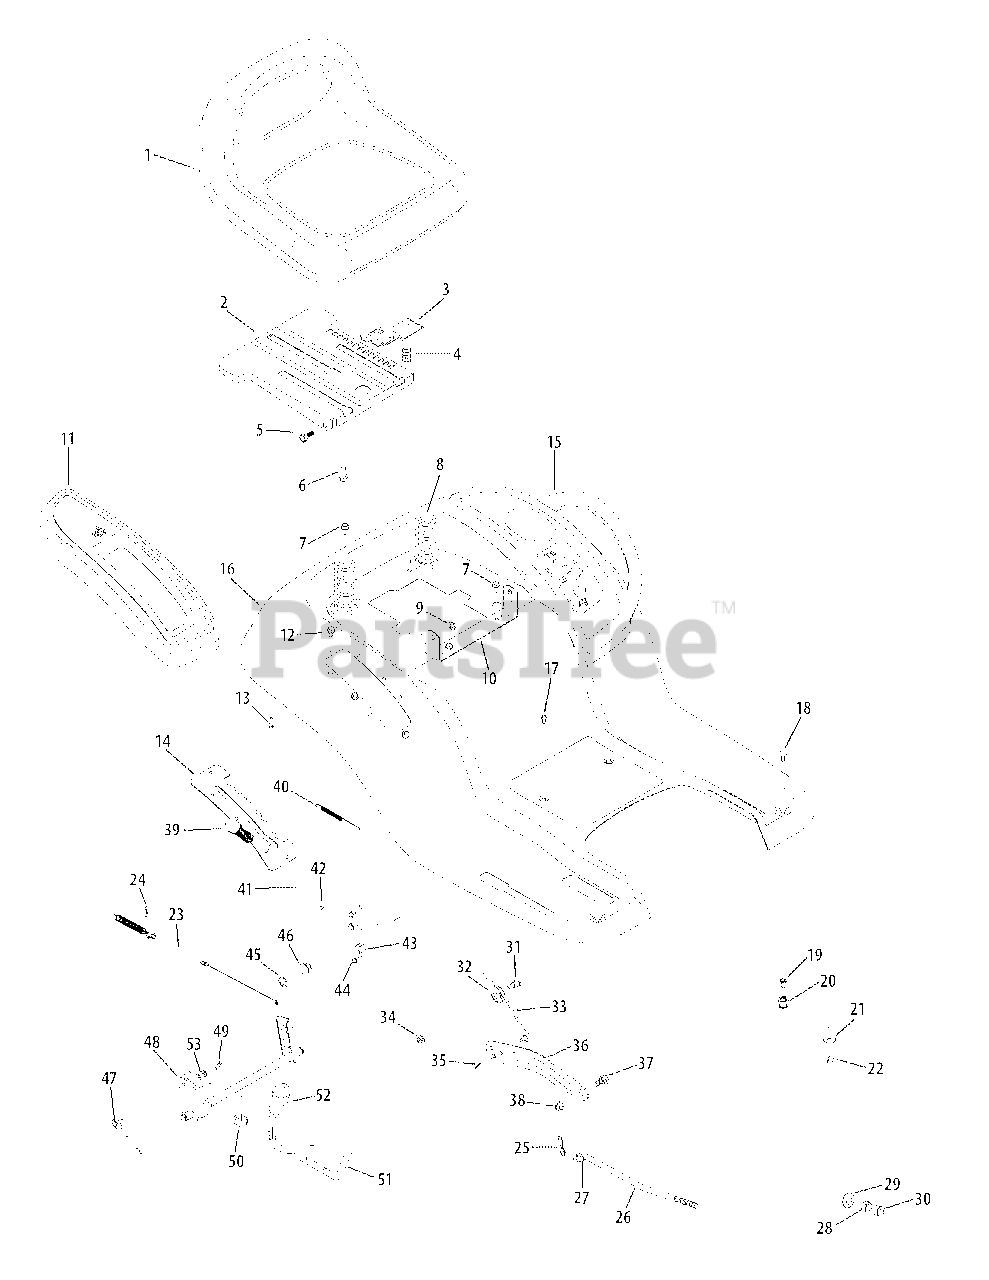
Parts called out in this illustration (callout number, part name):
1	Medium Back Seat
2	Seat Mounting Bracket
3	Seat Adjustment Lever
4	Compression Spring, .68 x 1.065 x .055
5	Shoulder Screw, 5/16-18 x .437 x .268
6	Hex Flange Bolt, 3/8-16 x .875
7	Hex Washer Screw, 5/16-18 x .750
8	Compression Spring, 1.71 x 3.735 x .238
9	Flange Lock Nut, 5/16-18
10	Seat Pivot Bracket
11	Fender Cover. RH
12	Hex Washer Screw, 5/16-18 x .750
13	Hex Washer Screw, 1/4-15 x .750
14	Manual PTO Lift Bracket
15	Fender Cover, LH
17	Hex Washer Screw, 1/4-20 x .500
18	Screw, 5/16-18 x 1.25
19	Flange Spacer, .3125 x .4375 x .625
20	Grommet, .4375 x .750
21	Flat Washer, .344 x 1.0 x .063
22	Flange Lock Nut, 5/16-18
23	PTO/Deck Engagement Cable
24	Bow-Tie Cotter Pin
25	Cotter Pin, 3/16 x 1.00
26	Deck Lift Rod
27	Flat Washer, 1/2 x 1.25 x .10
28	Bell Washer
29	Hex Nut, 1/2-13
30	Hex Lock Nut, 1/2-13
31	Shoulder Screw, 5/16-18 x .437 x .470
32	Cable Roller Pulley
33	Lift Cable
34	Flange Lock Nut, 5/16-18
35	Cotter Pin, 3/32 x 1.0
36	Lift Arm, LH
37	Shoulder Bolt, 3/8-16 x .625 x .175
38	Flange Lock Nut, 3/8-16
39	Grip
40	Extension Spring, .38 x 5.6
41	PTO Handle & Bracket Assembly
42	Shoulder Screw, #10-32 x .500
43	PTO Bearing
44	Hex Washer Screw, 1/4-20 x .500
45	E-Type Ring
46	Hex Flange Bearing
47	Lift Cable
48	Lift Shift Assembly
49	Cotter Pin, .072 x 1.13
50	Torsion Spring
51	Lift Handle
52	Handle Grip
53	Washer, .401 x .870 x .063
